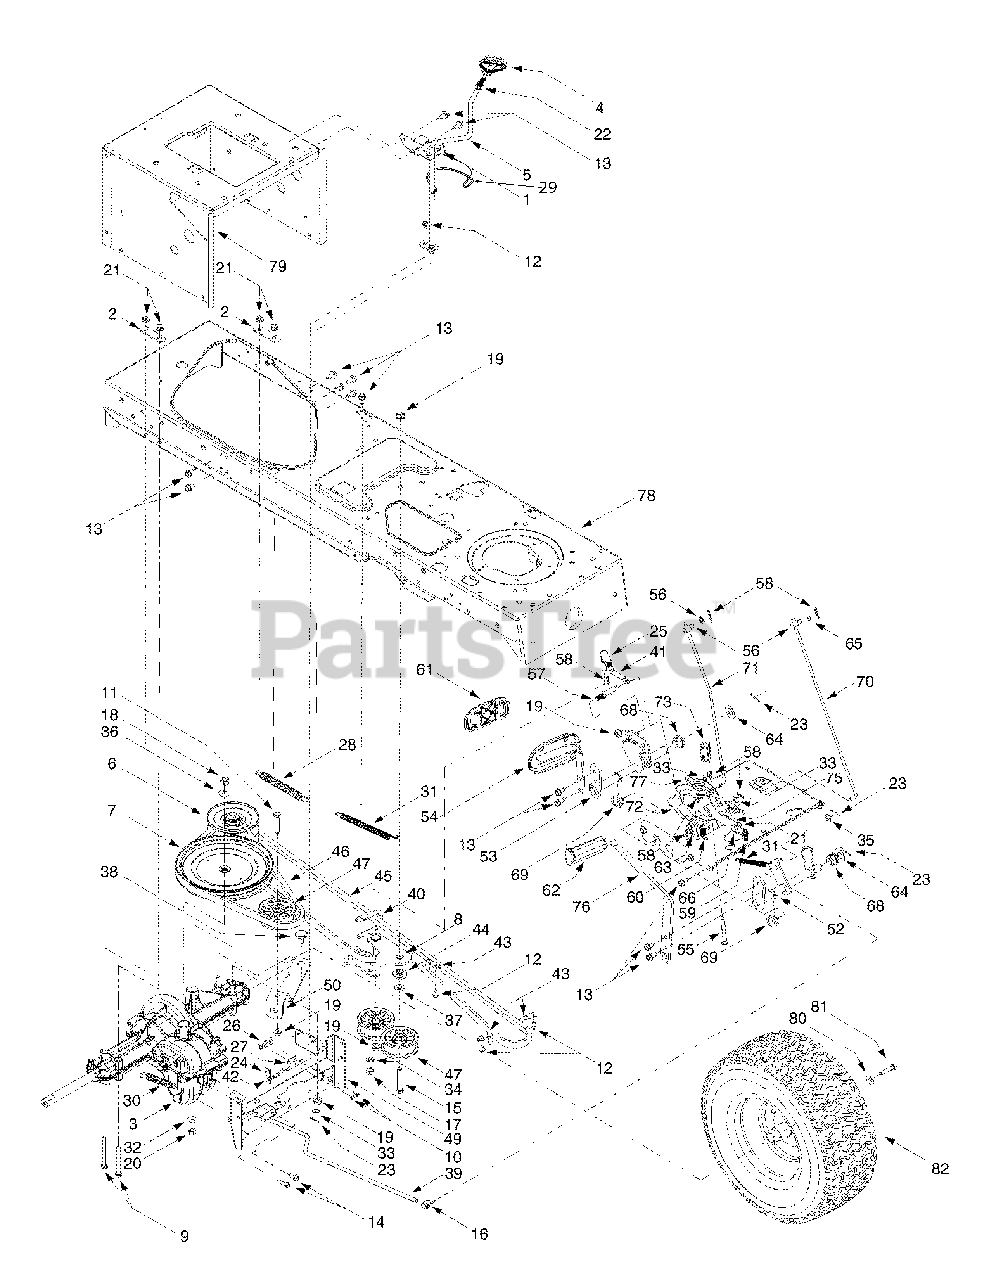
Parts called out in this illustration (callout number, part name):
1	Shift Lever Bracket
3	Single-speed Transmission Assembly
4	Shifter Knob
5	Shift Lever
6	Variable-speed Pulley Assembly
7	Transmission Pulley, 8.5 x .5-36
8	Double-idler Bracket
9	Hex Cap Screw, 5/16-18 x 3
10	Self Tapping Screw, #8-18 x .5
11	Hex Cap Screw, 3/8-16 x 1.75
12	Self Tapping Screw, 1/4-20 x .5
13	Self Tapping Screw, 5/16-18 x .625
14	Self Tapping Screw, 1/4-20 x .75
15	Hex Cap Screw, 3/8-16 x 2.25
16	Ferrule, 5/16-18
17	Hex Nut, 3/8-24
18	Hex Nut, 7/16-20
19	Flange Lock Nut, 3/8-16
20	Hex Nut, 3/8-16
21	Flange Lock Nut, 5/16-18
22	Jam Nut, 3/8-16
23	Cotter Pin
24	Internal Cotter Pin
25	Ball Joint, 3/8-24
26	Short Spring Switch
27	Insulator Nut Plate
28	Extension Spring, .62 Dia. x 6.12
29	Compression Spring Clip
30	Extension Spring, .59 OD x 4
31	Extension Spring, .50 Dia. x 6.37
32	Bell Washer, .401 x .87 x .063
33	Flat Washer, .385 x .62 x .063
34	Lock Washer, 3/8
35	Flat Washer, 5/16
36	Bell Washer, .45 x 1.0 x .602
37	Flat Washer, .407 x .812 x .135
38	Shoulder Screw, .625 x .217
39	Brake Rod
40	Belt Guard
41	Idler Adjustment Rod, 3/8
42	Shift Rod
43	Belt Guard Rod
44	Shoulder Spacer, .38 ID
45	Variable-speed Belt
46	Drive Belt
47	Flat Idler, 2.75 OD
48	Shift Lever Support
51	Adjustable Shift Bracket
52	Brake Control Assembly
53	Speed Control Assembly
54	Auto Drive - Pedal Assembly
55	Self Tapping Screw, 5/16-18 x 2.5
56	Ferrule, 1/4-20
57	Pin, 3/8-16 x 2.43
58	Cotter Pin
59	Compression Spring, .34 OD x 1.0
60	Extension Spring, .50 OD x 1.41
61	Auto Drive - Pedal Pad
62	Brake Pedal Pad
63	Flat Washer, .281 x .5 x .0625
64	Flat Washer, .64 x 1.24 x .06
65	Flat Washer, .344 x .062 x .03
66	Shoulder Screw, .437 x 1.62
67	Shoulder Screw, .5 x .434
68	Hex Flange Bearing
69	Split Hex Flange Bearing
70	Cruise Control Rod
71	Brake Lock Control Rod
72	Cruise Latch
73	Spacer, 5/16 x 1.54
75	Auto Drive - Lockout Bracket
81	Hex Cap Screw, 5/16-24 x .75
